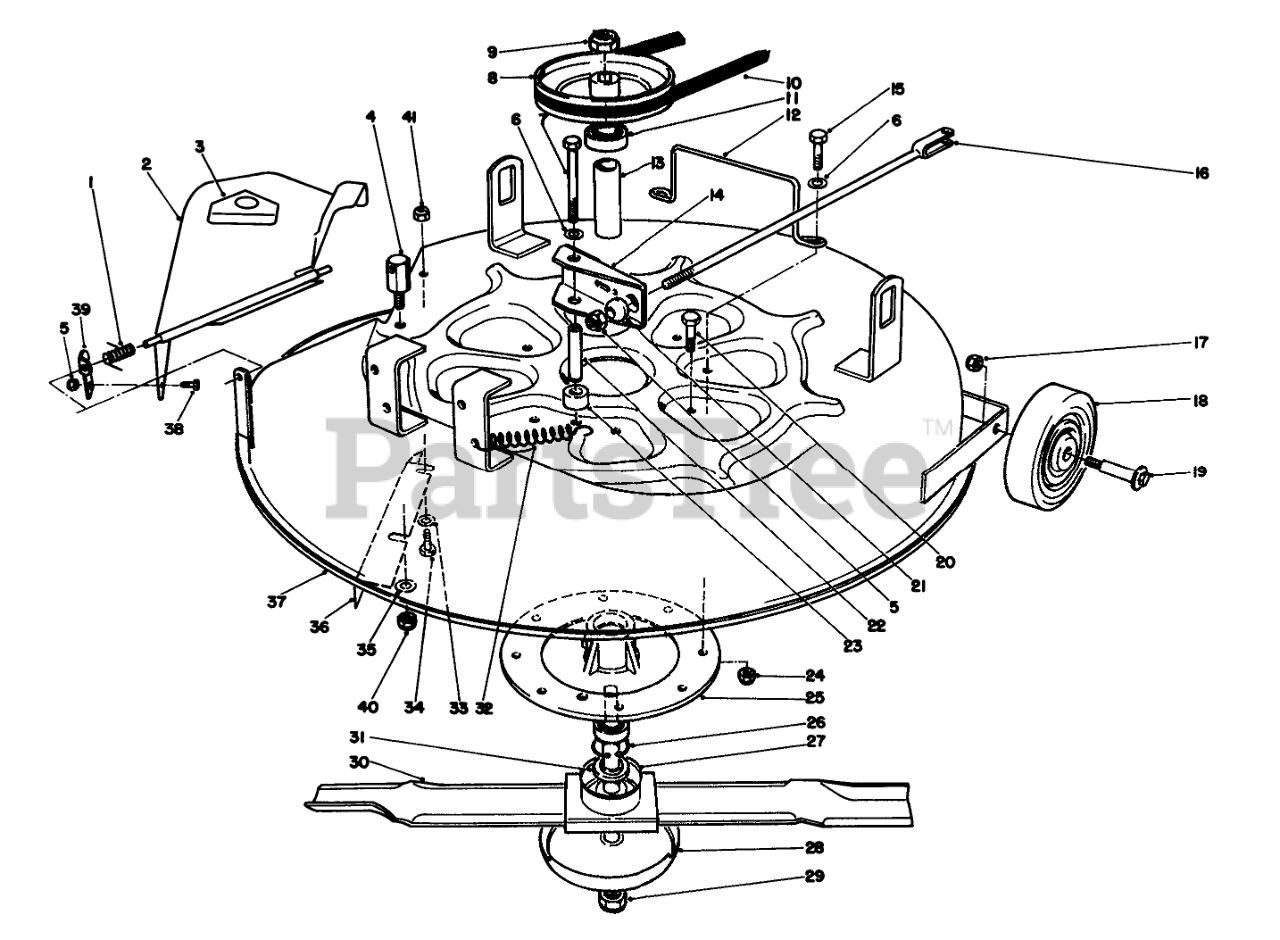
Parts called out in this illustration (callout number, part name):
1	SPRING
2	Deflector (Incl. Ref. #3)
3	DECAL-DANGER
4	POST-PIVOT
5	NUT-LOCK, NI
6	WASHER-PLAIN
7	SCREW-HH
8	DECK PULLEY
9	NUT-LOCK, NI
10	V-Belt
11	BEARING-BALL
12	DECK BELT GUIDE
13	SPACER-BEARING
14	DECK BRAKE ASSEMBLY
15	SCREW-HH
16	DECK BRAKE ROD WA
17	NUT-LOCK, NI
18	WHEEL-DECK
19	BOLT-WHEEL
20	SCREW-HH
21	BALL-SWIVEL, STOP
22	POST-BRAKE MTG
23	SPACER-DECK BRAKE
24	NUT-LOCK, NI
25	CASTING-SPINDLE
26	RING-RETAINING
27	Shaft-Spindle
28	Cup
30	Blade
31	SPINDLE SPACER
32	SPRING-EXTENSION
33	WASHER-FLAT
34	SCREW-HH
35	WASHER-FLAT
36	Baffle
37	Deck
38	SCREW-HH
39	Bracket-Detector
40	NUT-LOCK, NI
41	NUT-HEX
